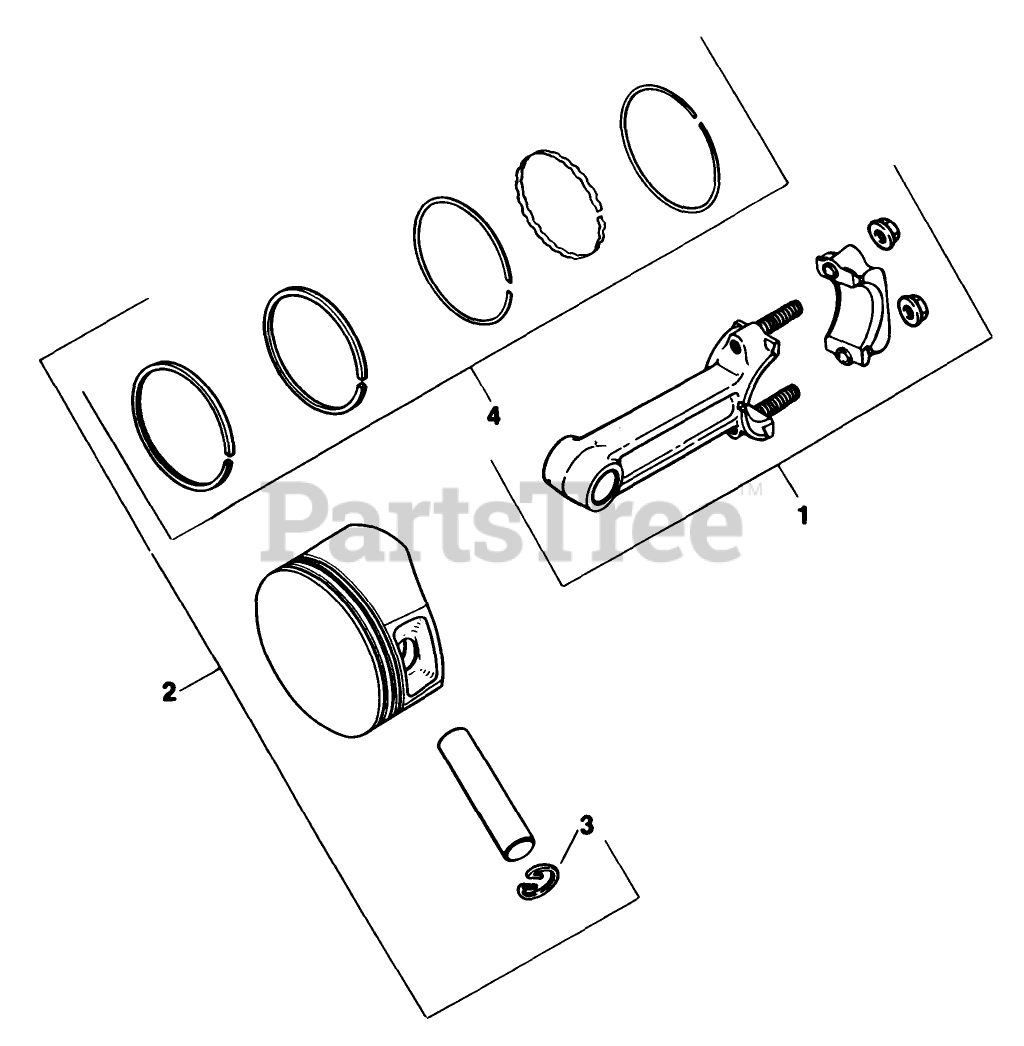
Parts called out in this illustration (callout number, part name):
1	Rod-Connecting Std.
1	Rod-Connecting .010"
2	Piston & Ring Set Std.
2	Piston & Ring Set .003"
2	Piston & Ring Set .010"
2	Piston & Ring Set .020"
2	Piston & Ring Set .030"
3	Retainer, Pin
4	Ring Set Std. & .003"
4	RingSet.010"
4	Ring Set .020"
4	Ring Set.030"
